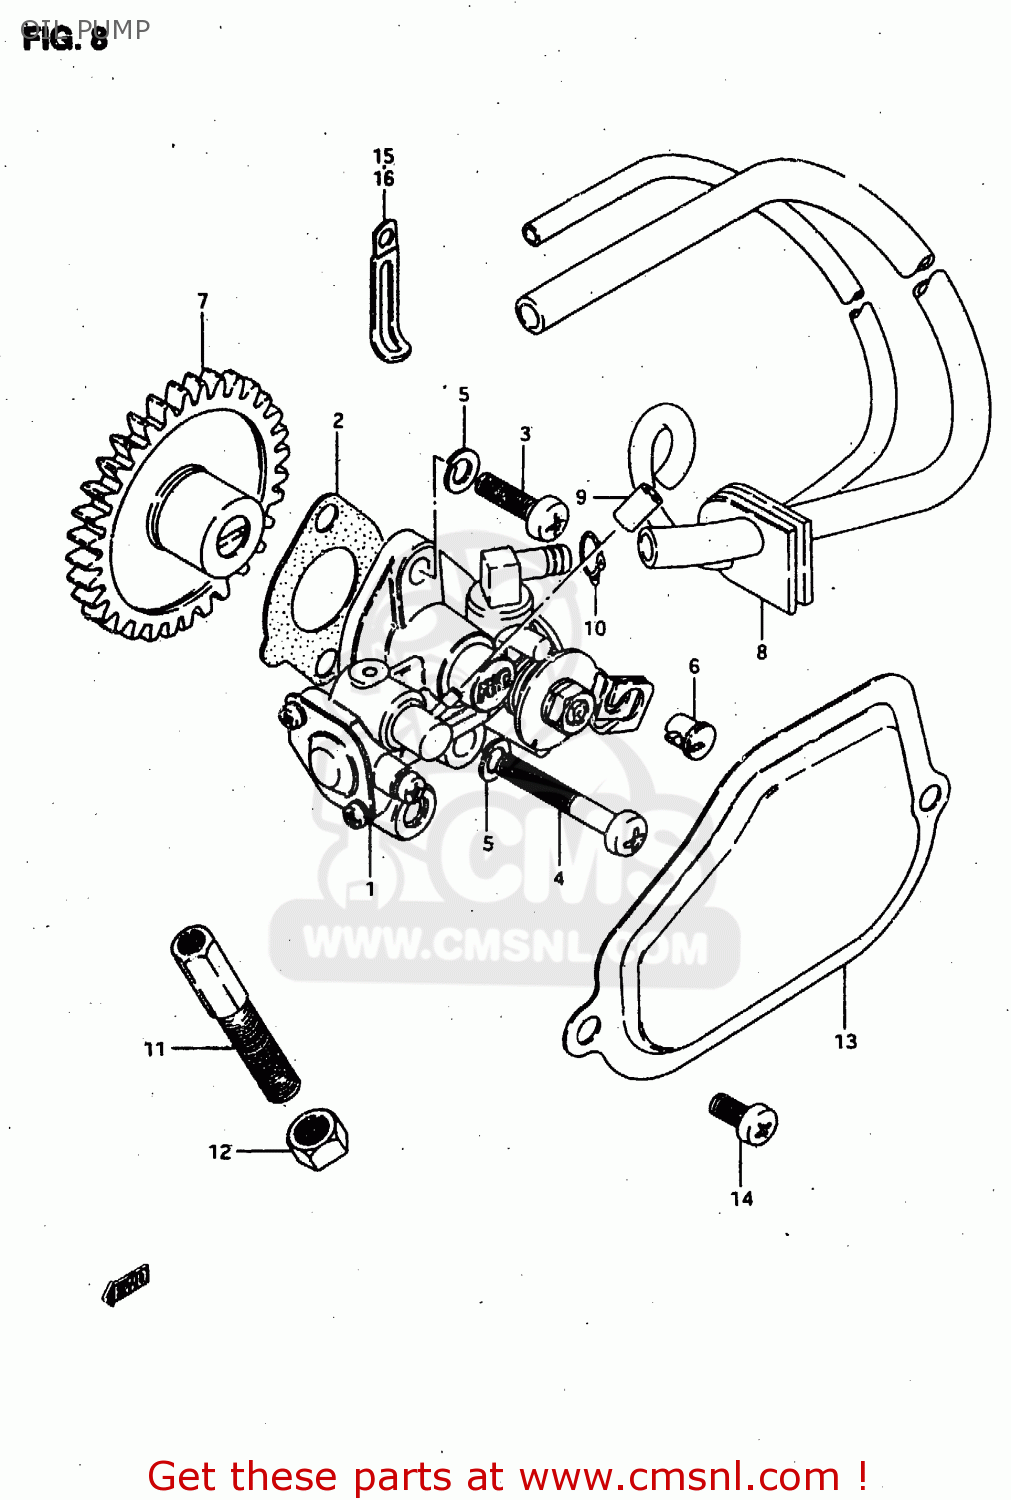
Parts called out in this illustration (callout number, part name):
1	PUMP ASSY,OIL
2	GASKET,OIL PUMP (NAS)
3	SCREW
4	SCREW
5	WASHER,LOCK
6	TERMINAL,CABLE
7	GEAR,OIL PUMP DRIVEN(NT:36)
8	HOSE,OIL
9	CLIP
10	CLIP
11	BOLT
12	NUT
13	CAP,OIL PUMP INSPECTION
14	SCREW
15	CLAMP(L:45)
16	CLAMP
